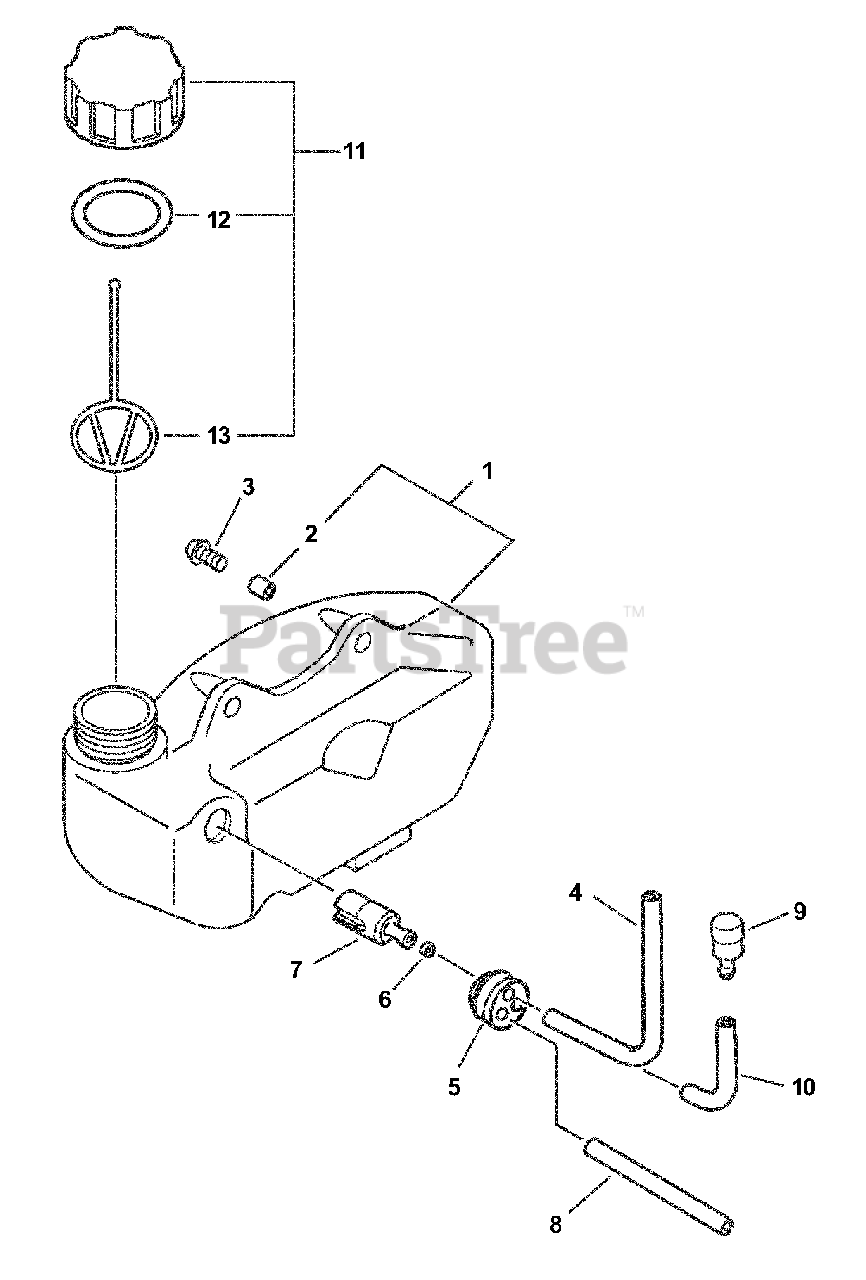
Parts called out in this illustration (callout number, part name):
1	TANK ASSY, FUEL
2	SPACER 6.2×7.8×6
3	SCREW 5×15
4	PIPE, FUEL
5	GROMMET, FUEL
6	CLIP 6 MM
7	FILTER, FUEL
8	PIPE, FUEL RETURN 3×6×110
9	VENT ASSY
10	PIPE, FUEL 3x-5x-70 BLACK
11	CAP ASSY, FUEL
12	GASKET, FUEL CAP
13	CONNECTOR, CAP L= 100 MM
